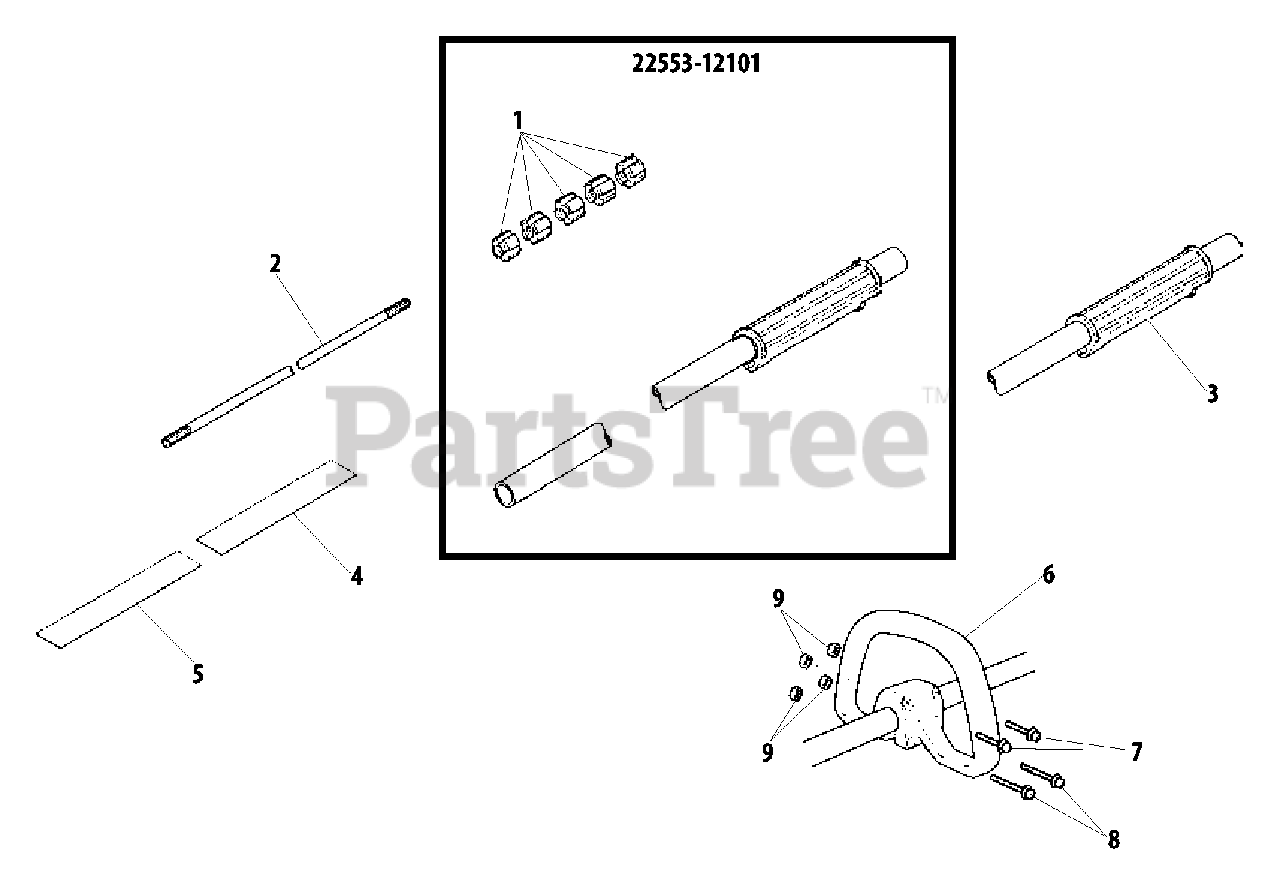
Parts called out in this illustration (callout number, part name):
1	BUSHING
2	PIPE, MAIN
3	GRIP
4	LABEL - CAUTION
5	NAME PLATE
6	HANDLE - FRONT
7	SCREW - 5X30
8	SCREW - 5X45
22553-12101	MAIN PIPE ASSY
